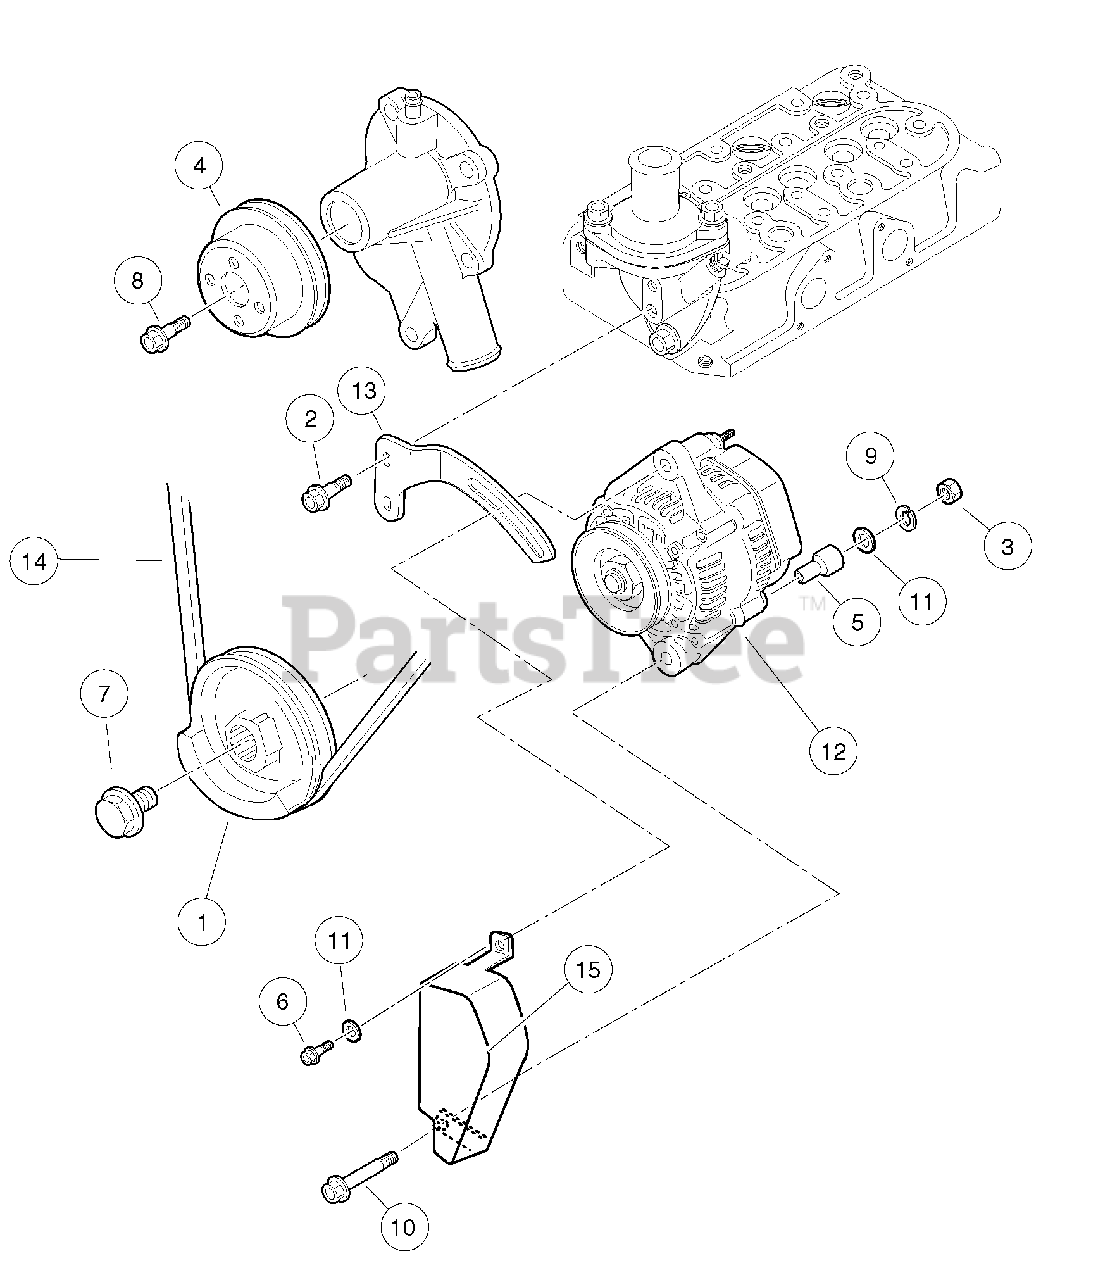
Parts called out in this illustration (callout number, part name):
1	Pulley, Fan Drive
2	Bolt, M6 X 1 X 20
3	Nut, M8, Plate
4	Pulley, Water Pump
5	Collar, Alternator Assy, D722
6	Bolt, Alt, D722, Adjuster
7	Bolt, Alt, D722, Drive Pulley
8	Bolt, D722, Drive Pulley
9	Washer, Spring, D722, Starter
10	Bolt, Alternator, Lower
11	Washer, Alternator, Upper
12	Alternator, 60 Amp
13	Brkt, Alt, D722, 60 Amp
14	Belt, Acc Drive, D722, 60 Amp
15	Guard, Acc Belt
